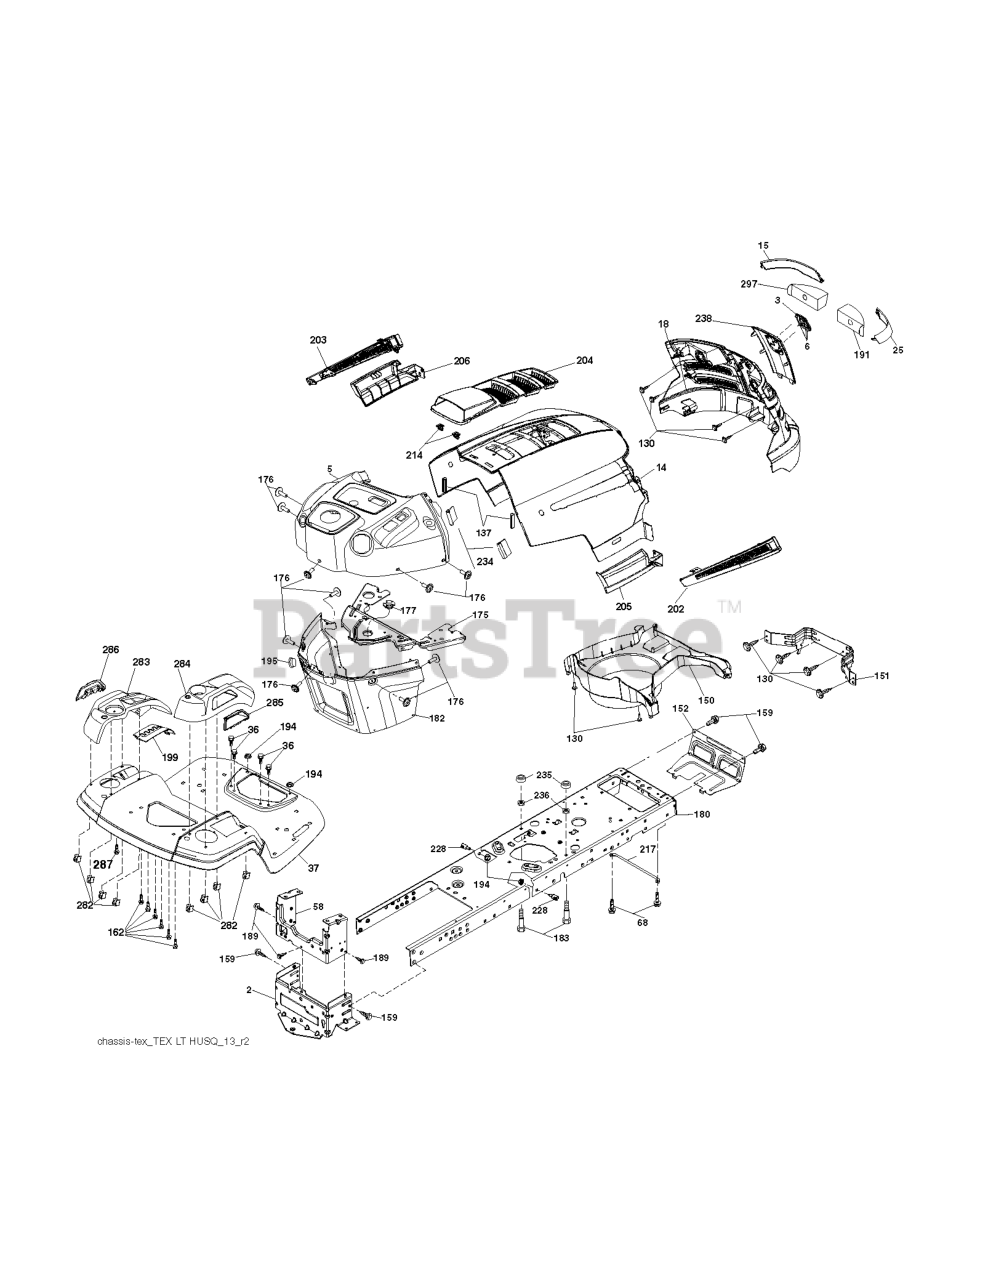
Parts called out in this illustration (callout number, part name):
2	DRAWBAR.LOWER.2PC.18/22
3	RP LOGO
5	DASH
14	HOOD.HUSQVARNA.LT.MS422
15	LENS.HUSQVARNA LT.LH
18	GRILLE.SVC.HUSQVARNA.LT.GREY
25	LENS.HUSQVARNA LT.RH
36	SCREW 5/16"
37	RP FENDER.TLT.FS.W/CPH.422
58	DRAWBAR UPPER 2PC SMALL FENDER
68	Screw 5/16-18 x 1/2 Hex, Self Tapping 5/16-18 x 1/2
130	SCREW.#10 X 0.750.BOS
137	BUMPER DASH
151	BRACKET PIVOT
152	SHIELD.BROWNING/DEBRIS
159	SCREW, 3/8-16X3/4
162	SCREW.HI-LO.CONSOLE
175	CROSSMEMBER
176	SCREW.#10-24X5/8.RN.QU
177	BUSHING STEERING
180	CHASSIS.STAMPING.LT/GT
182	DASH.LOWER.PREDATOR LT
183	BOLT.5/16-18X1-1/4 FULL.THREAD
189	SCREW
191	INSERT.REFLECTIVE.RH.
194	NUT LOCK HEX FLANGE 5/16-18
195	PLUG DASH
199	PLATE.DECK.LIFT.HUSQ.LT
202	VENT SIDE HOOD RH
203	VENT SIDE HOOD LH
204	VENT TOP HOOD
205	SKIRT SIDE RH
206	SKIRT SIDE LH
214	CLIP.RETAINER.TINNER.
217	ROD.PIVOT.HOOD
228	STUD.FASTNER.W/ANTI-ROTATE
234	BUMPER.HOOD.TEX.HUSQVARNA
235	SPACER FENDER
236	NUT.CENTERLOCK.5/16-
238	TRIM
282	CLIP.RETAINER.CONSOLE.LT.HUSQ
283	CONSOLE ASM.DCKLFT.N/F
285	CONSOLE INSERT RH
286	CONSOLE.INSRT.LH.HUSQ.LT.BLACK
287	SCREW 1/4X20
297	INSERT REFLECTIVE
